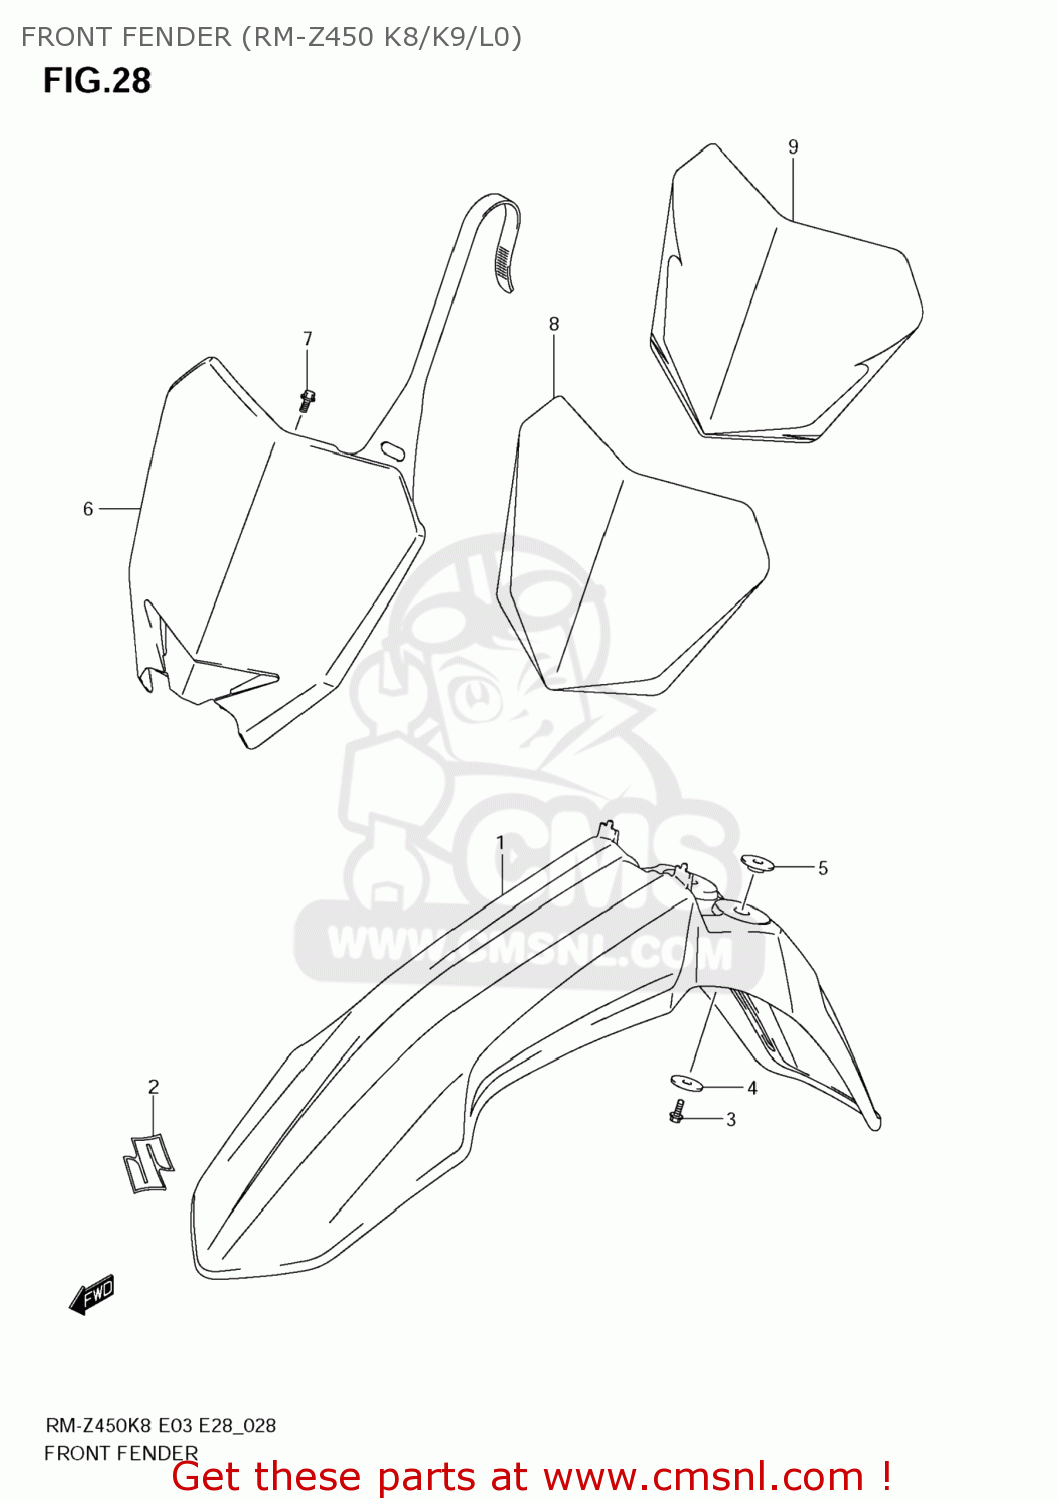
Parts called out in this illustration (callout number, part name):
1	FENDER,FR
2	EMBLEM,S
3	BOLT
4	WASHER,FUEL TANK FR
5	WASHER
6	PLATE,NUMBER F
7	BOLT(6X12)
8	TAPE,FR NUMBER PLATE
9	TAPE,FR NUMBER PLATE
